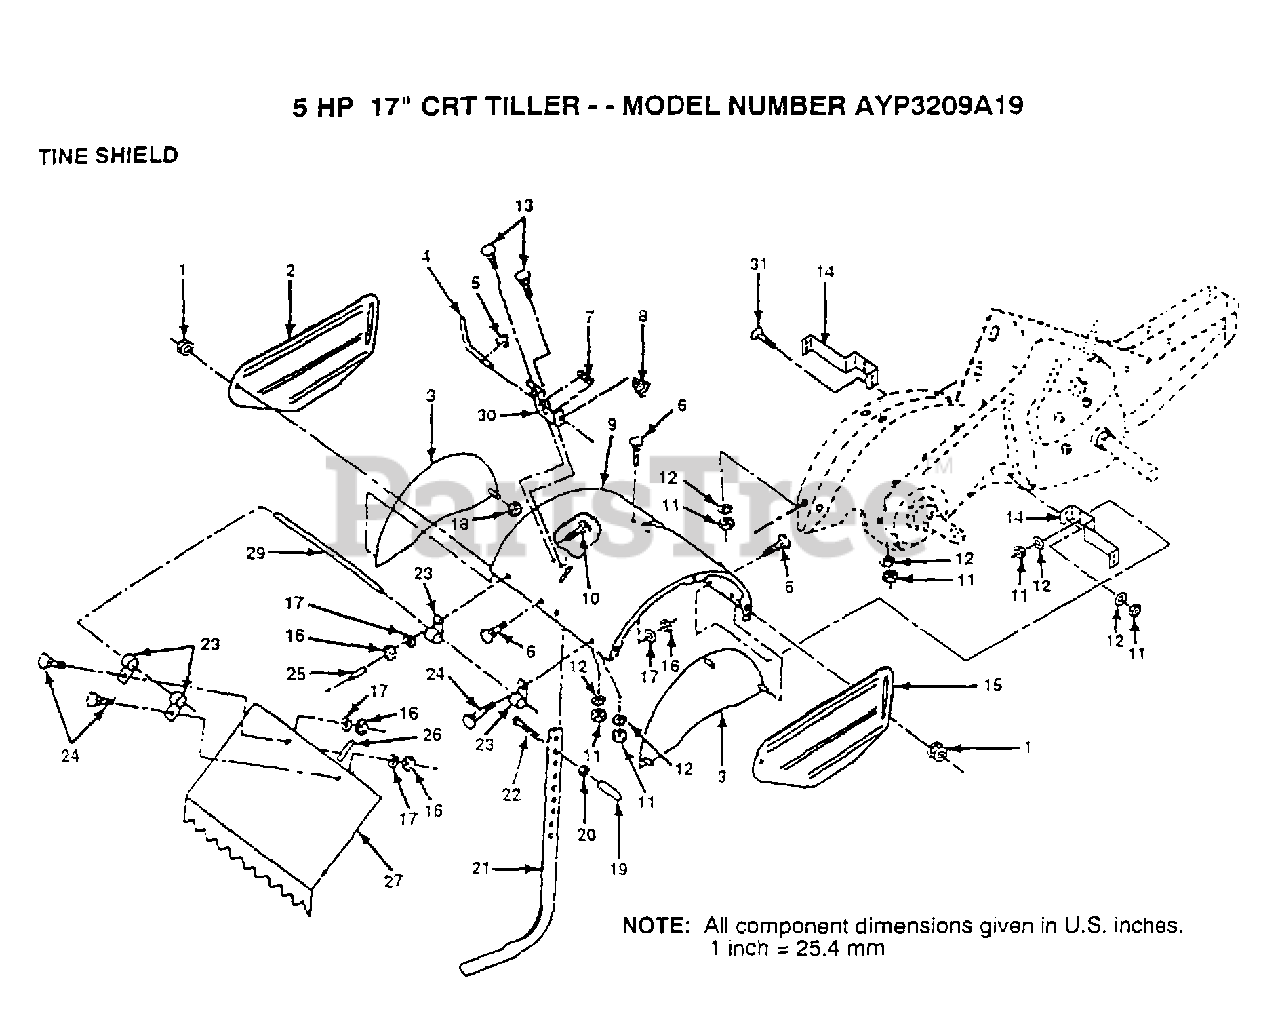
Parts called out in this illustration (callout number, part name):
1	NUT
3	SHIELD SIDE TI
4	STAKE PIN TI
5	KLIP RING TI
6	BOLT
7	SPRING TI
8	SPRING CRT
10	BOLT
11	NUT.HEX.5/16-18
12	LOCKWASHER
13	BOLT CRT
14	"BRACKET,SHIELD"
17	LOCKWASHER
18	LOCKNUT TI
19	GRIP CRT
20	NUT.HEX.3/8-16UNC
22	BOLT
23	HINGE CRT
24	BOLT
25	VINYL CAP TI
26	PAD IDLER TI
29	PIN HINGE
30	LATCH BRACKET TI
31	BOLT
